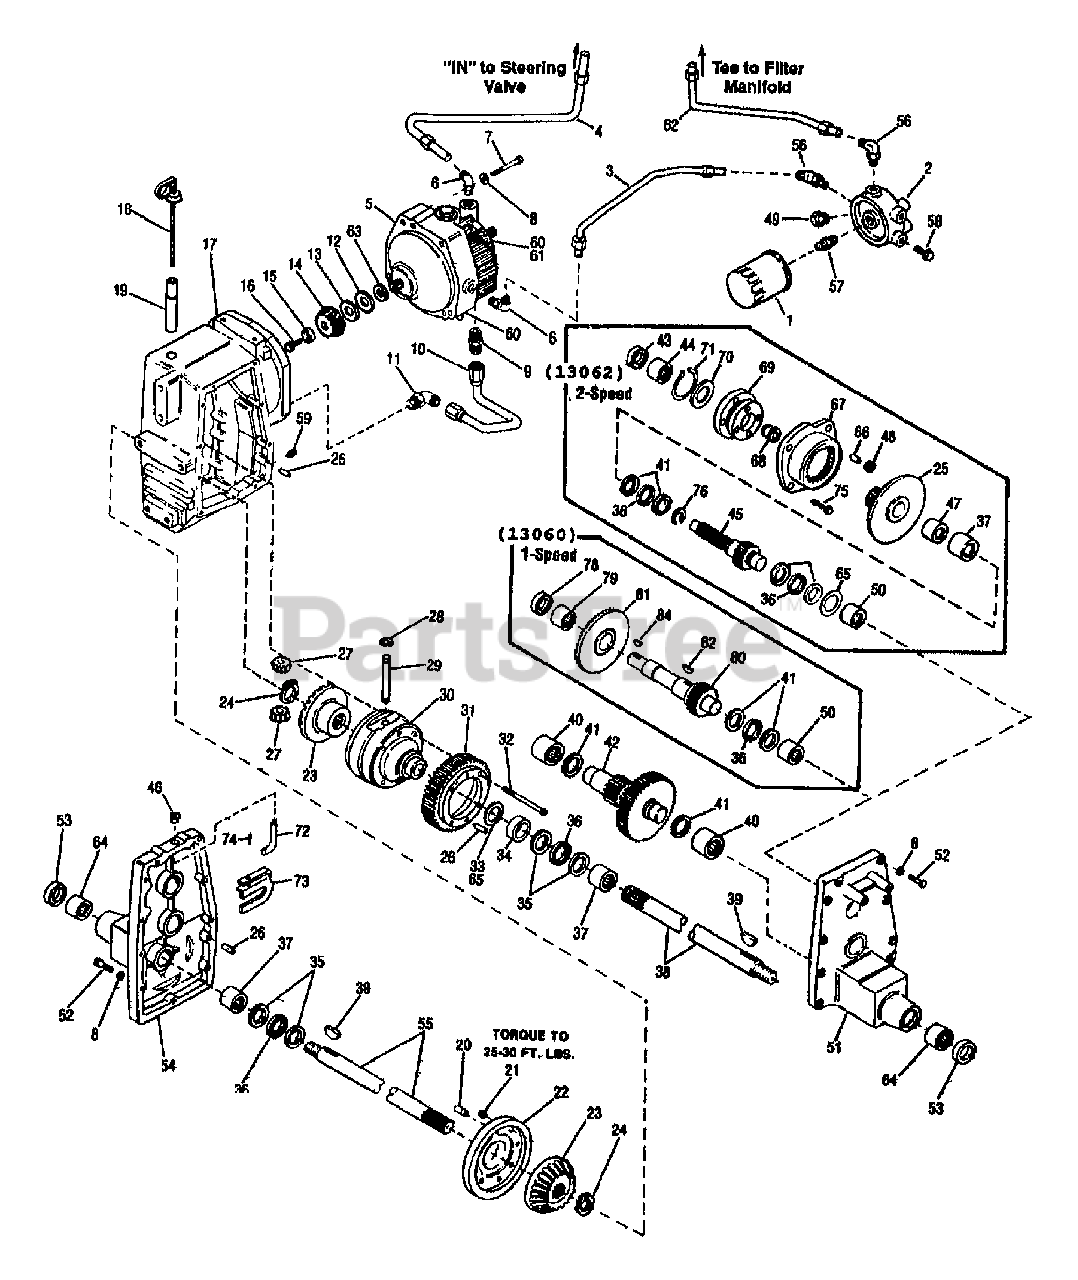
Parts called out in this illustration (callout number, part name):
1	FILTER-OIL
2	FILTER-MANIFOLD
3	ASSM-RETURN TUBE
4	ASSM-TUBE
5	EATON TRANS. MODEL 11
5	PUMP-HYDRO
6	ELBOW
7	SCR-HH 3/8-16X2.75 G5 ZP
8	WASHER-LK .375 @ DEPL
9	CONNECTOR
11	ELBOW
12	WASHER-SHIM
13	WASHER-SHIM
14	PINION-BEVEL
15	SPACER-1.0X.25X.25
16	SCR-HH 1/4-20X.625 G5 ZP
17	HOUSING-TRANSAXLE
18	DIPSTICK
20	PIN-.312X.75
21	NUT-HEX/LK 5/16-18 G5ZP
22	COVER-DIFFERENTIAL
23	GEAR-BEVEL 22T {13062}
23	GEAR-23T {13060}
24	RING-RET {13062}
24	RING-HEAVY EXT HD 1.0 ID {13060}
25	GEAR-BEVEL 23T 24T 56T {13062}
26	PIN-DOWEL .375X1.00 ZP
27	PINION-10T
28	RING-HEAVY EXT .625 ID
29	PINION-SHAFT
30	CARRIER-DIFFERENTIAL {13062}
30	CARRIER-DIFFERENTIAL {13060}
31	GEAR-AXLE 47T
32	SCR-HFLK 5/16-18X4.00 ZP
33	SHIM-1.75X1.26X.02 {13062}
33	SHIM-.005 {13062}
33	SHIM-1.875X1.013X.015 {13060}
34	SPACER-1.75X1.265X.432 {13062}
34	SPACER-1.5X1.01X.45 {13060}
35	RACE-THRUST {13062}
35	RACE-THRUST {13060}
36	BEARING-THRUST {13062}
36	BEARING-THRUST {13060}
37	BEARING-NEEDLE {13062}
38	AXLE-RH {13062}
38	AXLE-RH {13060}
39	KEY-WOODRUFF .312X1.12
40	BEARING-NEEDLE
41	RACE-THRUST {13062}
41	RACE-THRUST {13060}
42	GEAR CLUSTER {13062}
42	ASSM-GEAR CLUSTER {13060}
43	SEAL-OIL
44	BEARING-NEEDLE
45	SHAFT-PINION {13062}
46	SEAL-OIL {13062}
47	BEARING-BRONZE {13062}
48	GEAR-PLANET {13062}
49	SWITCH-TEMPERATURE {13062}
50	BEARING-NEEDLE {13062}
51	COVER-TRANS RH {13062}
51	COVER-TRANSAXLE RH {13060}
52	SCR-HH 3/8-16X1.5 G5 ZP
53	SEAL-OIL {13062}
53	SEAL-OIL {13060}
54	COVER-TRANS LH {13062}
54	COVER-TRANS LH {13060}
55	AXLE-LH {13062}
55	AXLE-LH {13060}
56	ELBOW
57	COUPLING
59	PLUG-PIPE
60	SEAL-OIL
61	SHIELD-GRASS
62	ASSM-TUBE
63	WASHER-1.0X.64X.029
64	BEARING {13062}
64	BEARING-NEEDLE {13060}
65	SHIM-.005 {13062}
66	PIN {13062}
67	GEAR-INTERNAL RING {13062}
68	GEAR-SLIDING {13062}
69	CARRIER-PLANET {13062}
70	WASHER-THRUST {13062}
71	RING-RET. INT 4 DIA {13062}
72	SHAFT-SHIFTER {13062}
73	PLATE-SHIFTER {13062}
74	PIN-ROLL .156X.75 {13062}
75	SCR 5/16-18X1.00 {13062}
76	RING-POSITIONING {13062}
78	SEAL-OIL {13060}
79	BEARING-NEEDLE {13060}
80	ASSM-PINION SHAFT {13060}
81	GEAR {13060}
82	KEY-WOODRUFF .25X1 {13060}
84	KEY-WOODRUFF .25X.75 {13060}
